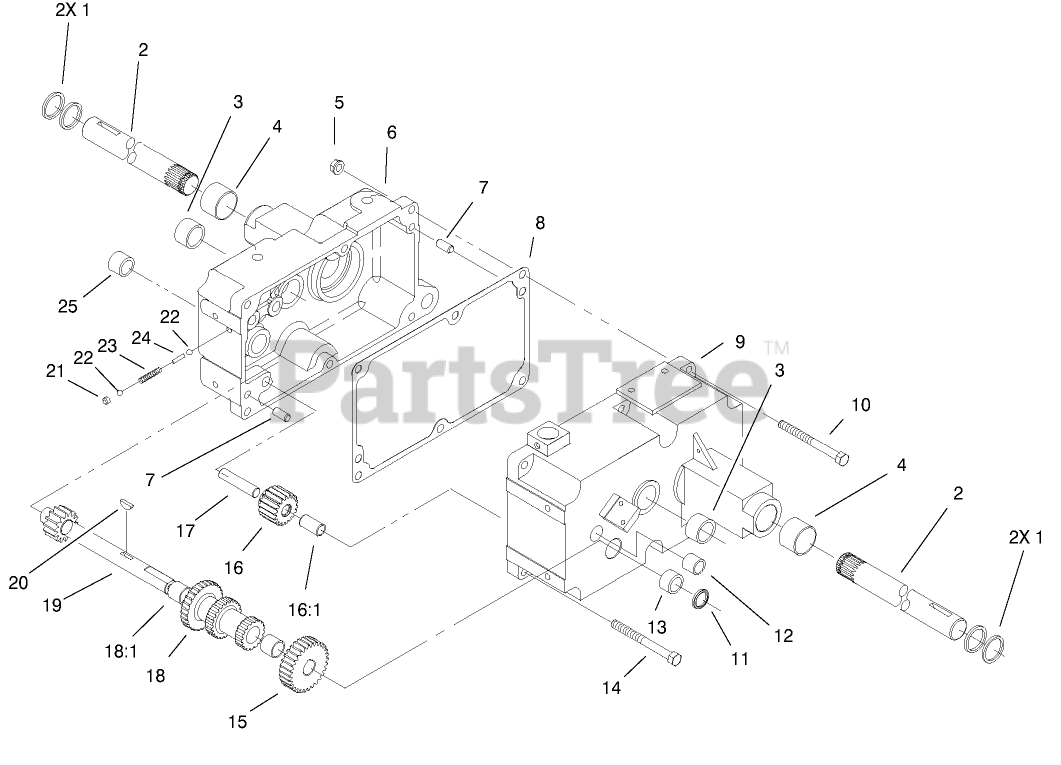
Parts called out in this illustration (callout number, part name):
1	SEAL-OIL
2	AXLE-REAR
3	BEARING-NEEDLE
4	BEARING
5	NUT-LOCK, NI
6	CASE-RH TRANS
7	PIN-DOWEL
8	GASKET-TRANSMISSION
9	CASE-TRANS LH
10	SCREW-HH
11	SEAL-OIL
13	BEARING-NEEDLE
14	SCREW-HH
15	GEAR-CLUSTER SHAFT
16	GEAR/BUSHING ASM-REVERSE IDLER
16:1	BUSHING
17	PIN-DIFFERENTIAL
18	GEAR-CLUSTER
18:1	BUSHING-BRONZE
19	SHAFT-CLUSTER
20	KEY-WOODRUFF
21	CUP-PLUG
22	BALL-DETENT
23	SPRING-SHIFT STOP
24	PIN-SHIFT
25	BEARING-NEEDLE
